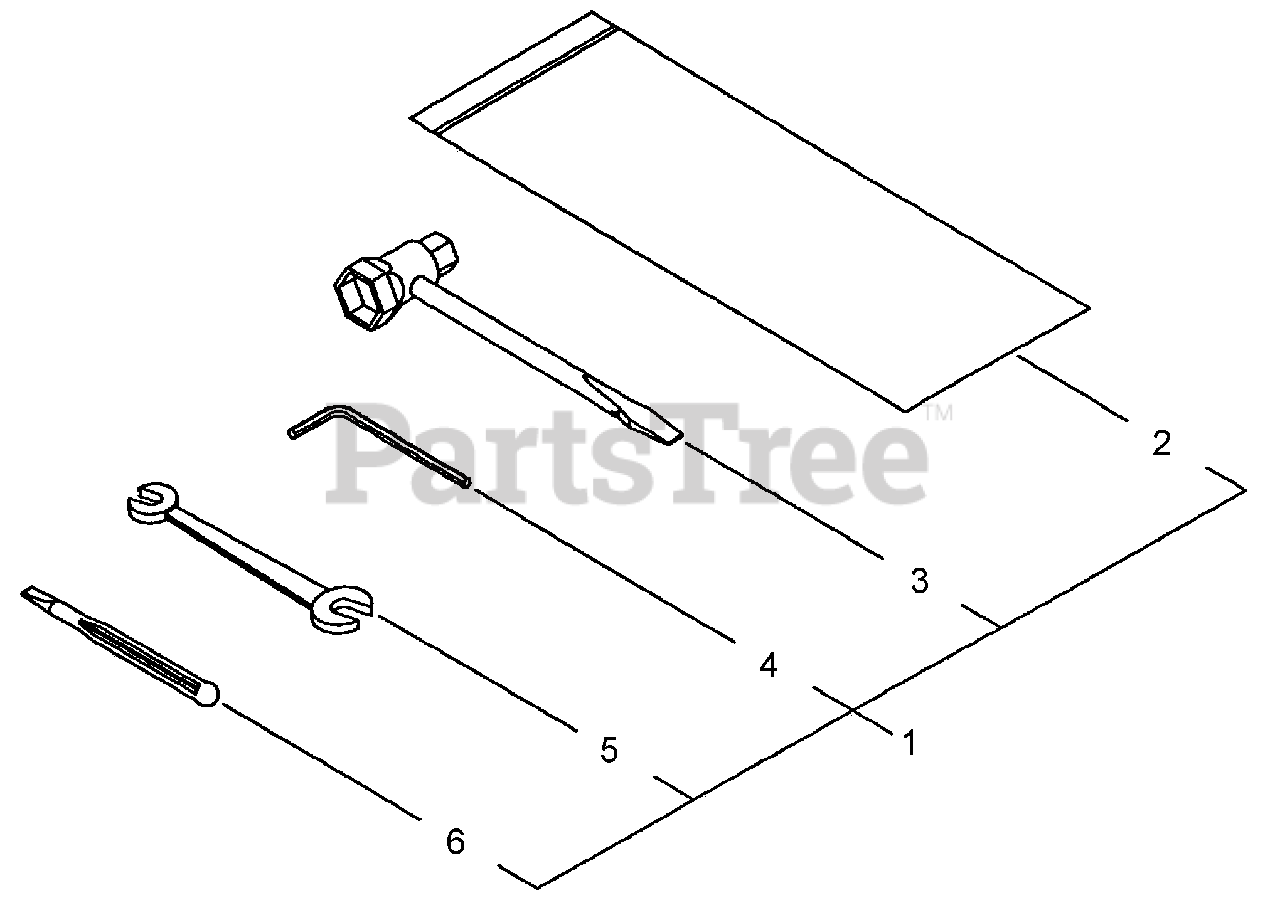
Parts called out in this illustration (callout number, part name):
1	SERVICE TOOL KIT
2	BAG, TOOL
3	T-WRENCH 13×19 MM
4	WRENCH, ALLEN 3 MM
5	WRENCH, ALLEN 4 MM
6	SCREWDRIVER, PLASTIC
